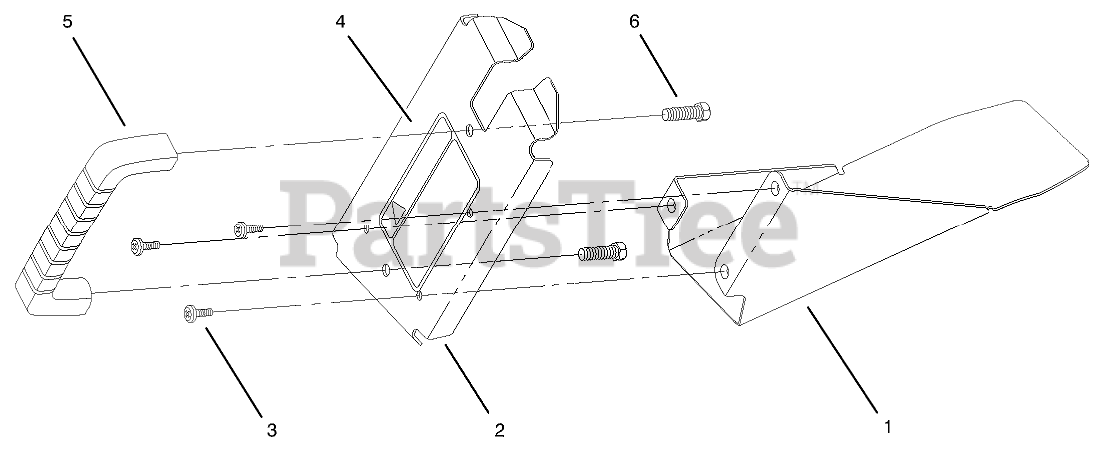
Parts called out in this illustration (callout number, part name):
1	Shield-Discharge Plug
2	Cover-Discharge Plug
4	DECAL - WARNING
5	HANDLE-DOOR
6	SCREW-HWH
